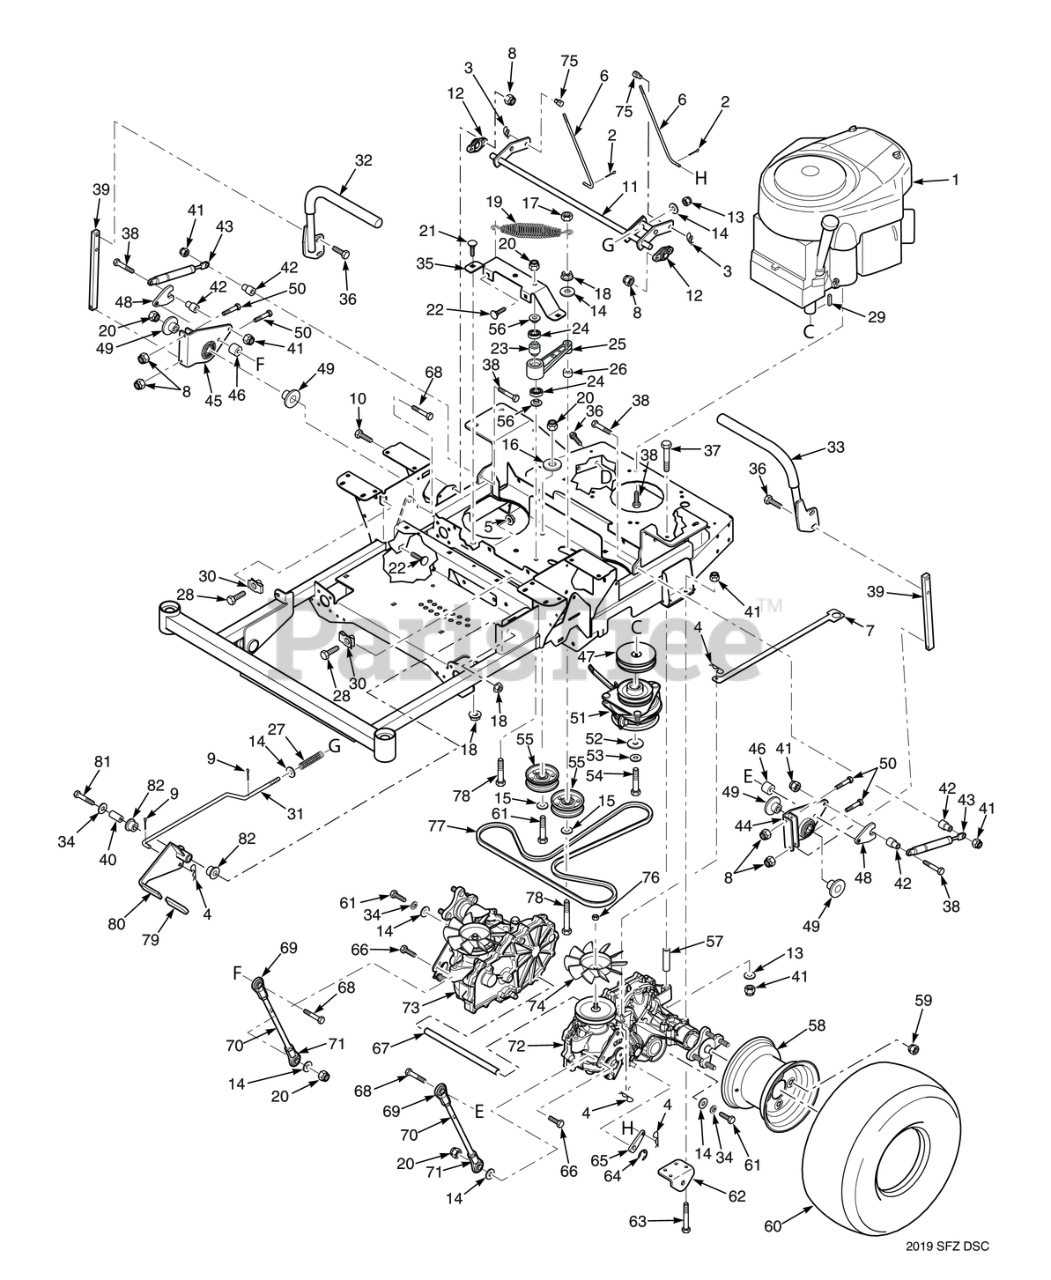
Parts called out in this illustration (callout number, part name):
1	Engine, Kohler 24KT
2	COTTER PIN, 3/32 X 1"
3	Pin, Rue Cotter 3/8" Diameter
4	HAIR PIN, .08 DIAMETER X 1-3/16"
5	Nut, Serrated Flange 5/16-18 (Right Front Engine Mounting, Briggs and Kohler Only)
6	Rod, Brake Adjustment
7	Lever, Dump Valve
8	Nut, Flanged Elastic Stop 1/4-20
9	COTTER PIN, HAIR - 0.94 X 1.62
10	CAP SCREW, 1/4-20 X 1" SERRATED FLANGE HEX
11	Weldment, Brake Lever
12	Bearing
13	Flatwasher, 5/16-.375 x .875 x .083 (35BV & 37BV-EFI)
14	Flatwasher, 3/8" Special (.391 x .938 x .105)
15	Flatwasher, 3/8 (.391 x .938 x .105 HD) Grade 8
16	Flatwasher, 3/8-.406 x 1-1-1/2 x 7 Gauge
17	Bolt, Hex Head 3/8-16 x 1" Ser. Flg.
18	NUT, 3/8-16 SERRATED FLANGE HEX HEAD
19	Spring, Transmission Idler
20	HEX NUT, ELASTIC STOP LOCK, 3/8-16
21	Bolt, Carriage 3/8-16 x 3/4"
22	Bolt, 5/16-18 x .75 RHSN Carriage
23	Spacer, Bearing
24	BEARINGS, BALL, NEUTRAL RETURN
25	Trans. Idler Arm Assy. (Includes 24, 79)
26	Spacer, Idler Pulley - SFZ52
27	Spring, Brake
28	Bolt, Hex Head 3/8-16 x 1-1/4" Special Lock
29	KEY, 1/4 X 1/4 X 3/4"
30	U-Nut, 3/8-16 (short)
31	Rod, Brake Linkage
32	Handle Bar Assembly RH, w/Grip
33	Handle Bar Assembly LH, w/Grip
34	Flatwasher, 3/8" Special (.391 x .938 x .105)
35	Support, Idler Arm
36	Capscrew, 3/8-16 x 1.0" Serrated Flange Hex Hd
37	HEX HEAD BOLT, 5/16-18 X 5"
38	Bolt, Hex Head 5/16-18 x 1-1/2" (Right Front Engine Mounting, Briggs and Kohler Only)
39	Bar, Control Lever
40	Pivot, Brake Lever
41	HEX NUT, ELASTIC STOP LOCK, 5/16-18
42	Spacer, Pump Dampener
43	Damper, Steering
44	Control Link, LH
45	Control Link, RH
46	Spacer, Idler Pulley - SFZ52
47	Pulley, 4-1/2" Dia. 1" Bore
48	Nut, Control Linkage
49	Spacer, Linkage
50	Bolt, Hex Head, 1/4-20 x 1-1/2"
51	Electric Clutch Assembly
52	Flatwasher, 7/16-.469 x 1.75 x .25 (48, 52)
53	Lockwasher, 7/16� Spring
54	Bolt, Hex Head 7/16-20 x 2-1/4" w/Patch (Kawasaki)
55	Pulley, 3-1/2" Dia.
56	Spacer, Controls
57	Spacer, Axle - SFZ52
58	Rim w/Valve Stem
59	Wheel Nut, 1/2-20 x 13/16
60	Wheel Assembly (INCL.58)
61	Capscrew, Hex Head 3/8-16 x 2-1/2"
62	Bracket, Push Arm Link
63	Bolt, Hex Head 5/16-18 x 3.00"
64	Ring, Retaining External .375"
65	Lever, Brake (order through Hydro-Gear)
66	Bolt, Hex Head, 3/8-16 x 1-1/2"
67	Spacer, Axles
68	Capscrew, Hex Head 3/8-16 x 2.0"
69	Rod End, 3/8-24 UNF LH
70	Linkage, Pump
71	Rod End, 3/8-24 UNF RH
72	Transaxle Assy., LH (ZK-KCBC-SLKG-3NTX)
73	Transaxle Assy., RH (ZK-GCBC-SLKF-2NTX)
74	Fan (order through Hydro-Gear)
75	Joint, Swivel
76	Fan Nut (order through Hydro-Gear)
77	Belt, Transmission Drive - SFZ52
78	Capscrew, Hex Head 3/8-16 x 3.25"
79	Grip, Brake Handle
80	Brake Handle Assembly
81	Capscrew, Hex Head 3/8-16 x 2-1/2"
82	Bearing
